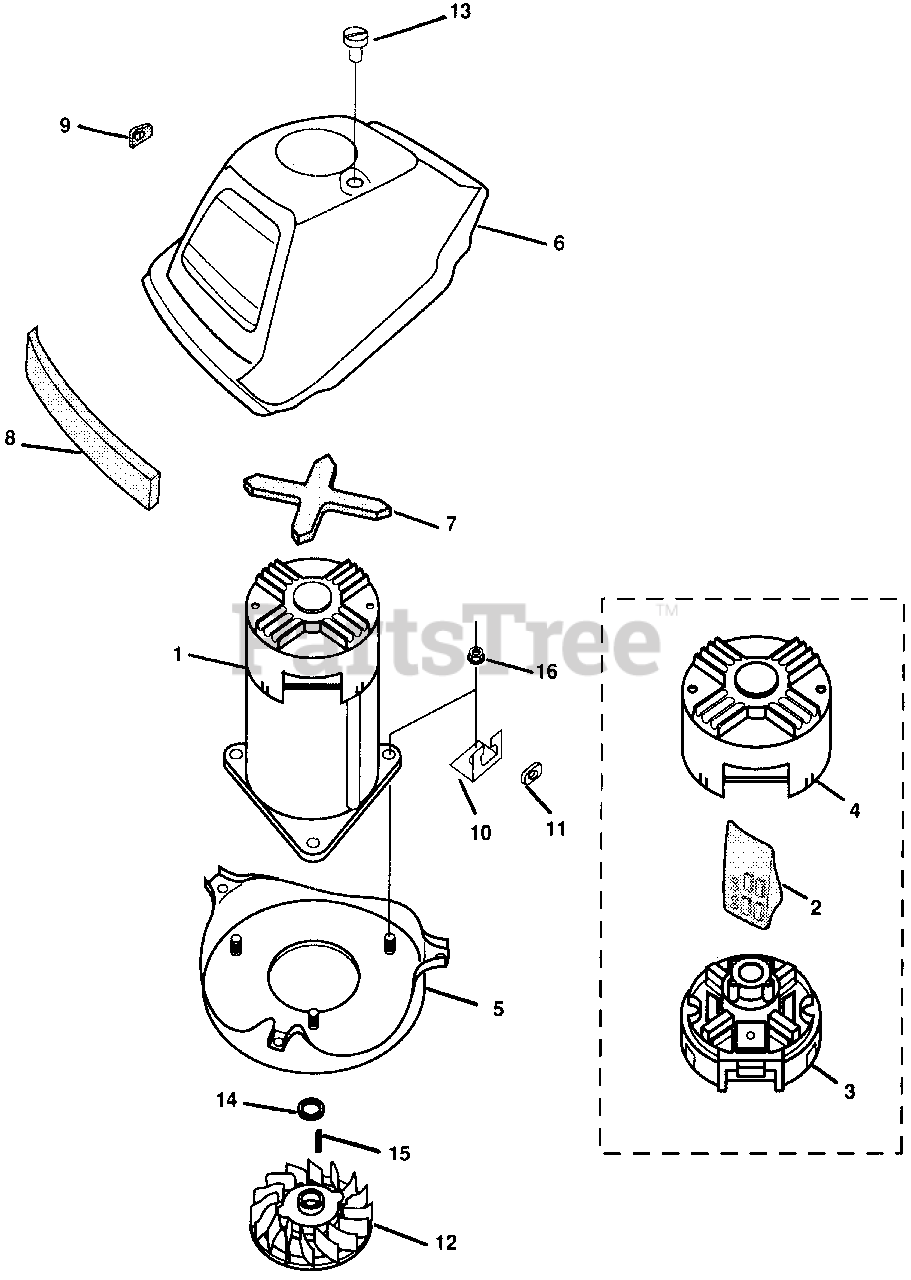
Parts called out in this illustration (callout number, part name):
1	MOTOR ASSY. (NOT AVAILABLE)
2	HOLDER, BRUSH
3	HOLDER, BRUSH
4	COVER, BRUSH HOLDER
5	BASE, MOTOR
6	COVER, MOTOR *R8* (BRIGHT RED)
7	FILTER, MOTOR (NOT AVAILABLE)
8	FILTER, MOTOR COVER
9	GROMMET, WIRE
10	CLIP, WIRE
11	BUSHING, WIRE
12	FAN, COOLING (NOT AVAILABLE)
13	NUT, MOTOR COVER
14	WASHER (17.3X25)
15	KEY, SQUARE
16	NUT, FLANGE (6MM)
